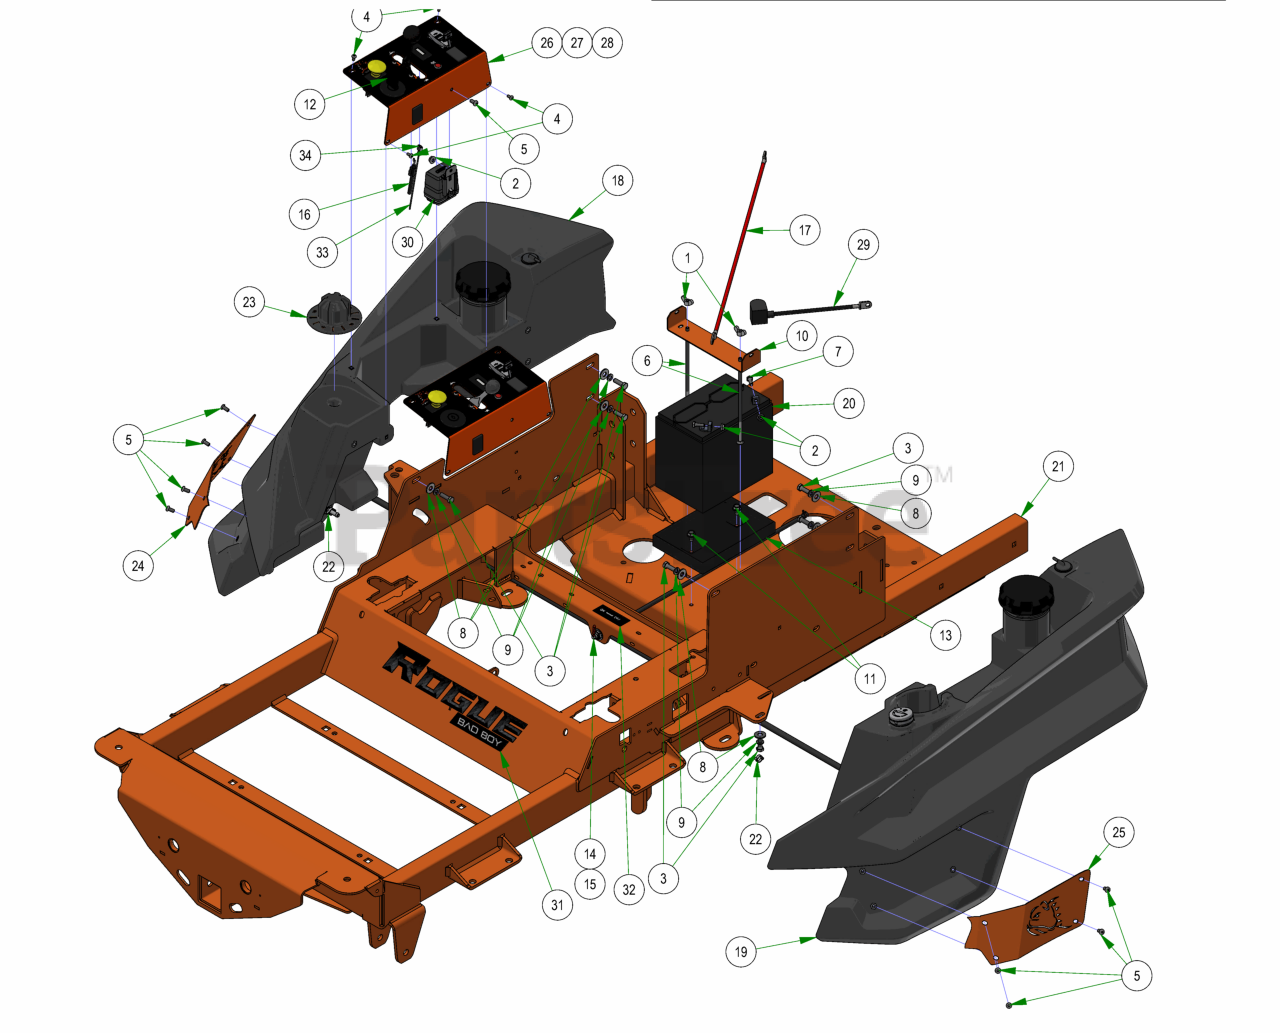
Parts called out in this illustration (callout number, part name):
1	1/4-20 WING NUT FORGED (TYPE A) LIGHT SERIES ZINC
2	1/4-20 HEX SERRATED FLANGE NUT HARD/ZINC
3	5/16-18 X 1 HEX CAP SCREW (GR.5) ZINC
4	10-32 X 3/8 BUTTON SOCKET CAP SCREW 18-8 STAINLESS STEEL
5	1/4-20 X 1/2 BUTTON SOCKET CAP SCREW 18-8 STAINLESS STEEL
6	1/4-20 X 8 CARRIAGE BOLT (MIN 6" THREAD) ZINC
7	1/4-20 X 3/4 HEX CAP SCREW (GR.5) ZINC
8	5/16 USS FLAT WASHER (7/8 OD) ZINC
9	5/16 SPLIT LOCKWASHER ZINC
10	2023 Rogue Battery Hold Down Plate
11	5/16-18 X 1/2 HWH unslot (F) tcs zinc
12	Ignition Key
13	Battery Tray
14	2023 Rebel Rogue Renegade Fuel Line for Kohler
15	2023 Rebel Rogue Renegade Fuel Line for Kawasaki
16	Outlaw Throttle Cable
17	24" Red Battery Cable
18	2019 Right Rebel, Rogue, Renagade Fuel Tank (GAS)
19	2019 Left Rebel, Rogue, Renegade Fuel Tank (GAS)
20	SP-35 Battery
21	2023 Rogue Frame - Painted
22	2 EAR CLAMP 12.5mm-15mm
23	2019 Deck Height Dial
24	2019 Outlaw Fuel Tank Insert - Right
25	2019 Outlaw Fuel Tank Insert - Left
26	Rebel/Rogue EFI Control Panel Assy
27	Rebel/Rogue Control Panel Assy
28	Rebel/Rogue Control Panel Assy-Drive by Wire
29	Starter Cable
30	2019 Wiring Harness-Rebel/Rogue
31	Rogue back Plate & Front Decal
32	R-Series Shut Off Valve Decal
33	16 AWG Black Insulated Wire for Tachometer
34	1/4" Female Quick Connect Terminal
